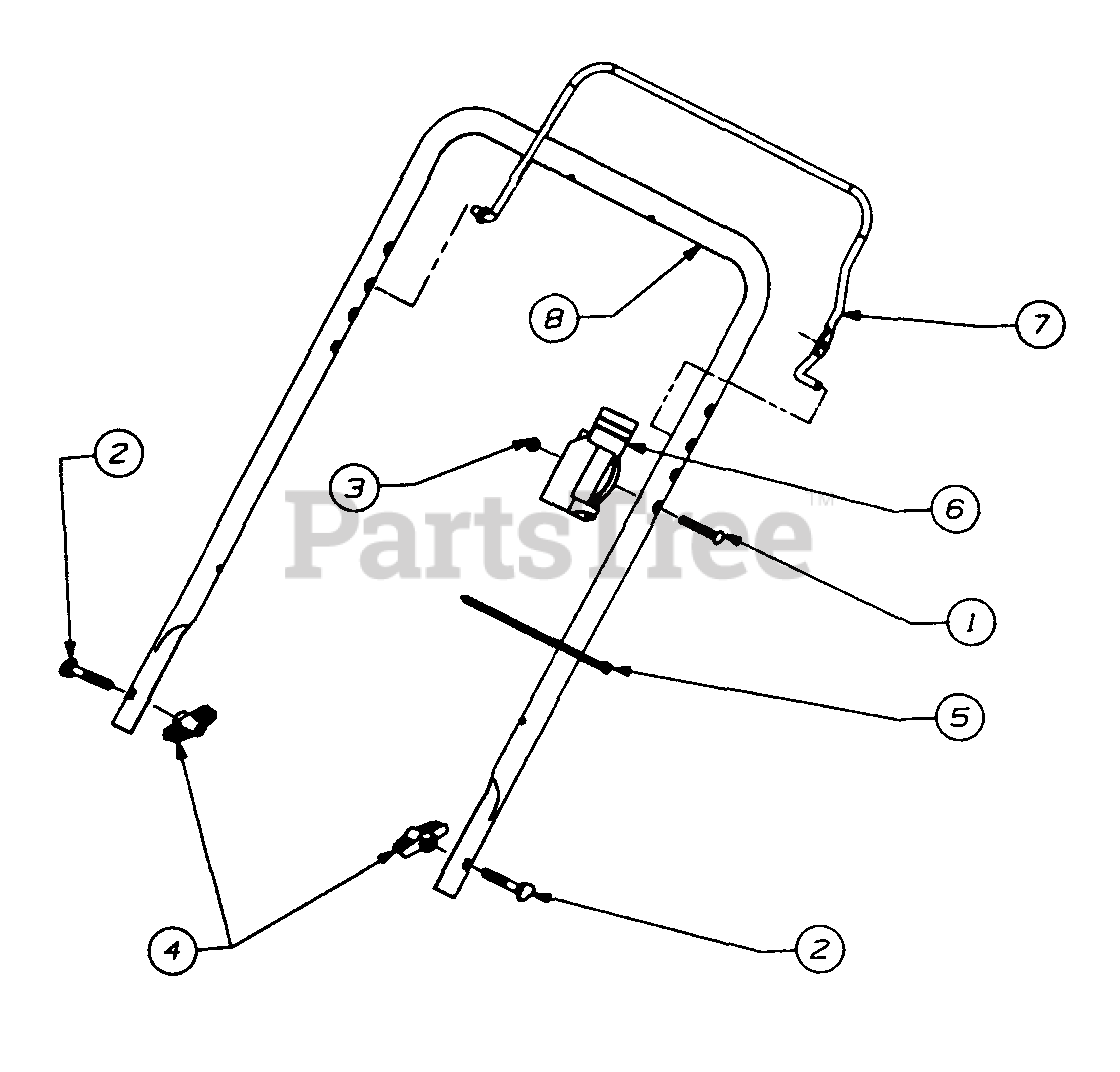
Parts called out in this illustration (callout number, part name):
1	Screw - Oval C-Sink L
2	Bolt Carriage
3	Nut Insl. Lock
4	Knob - Handle
5	Tie Cable
6	Body - Lever Control
